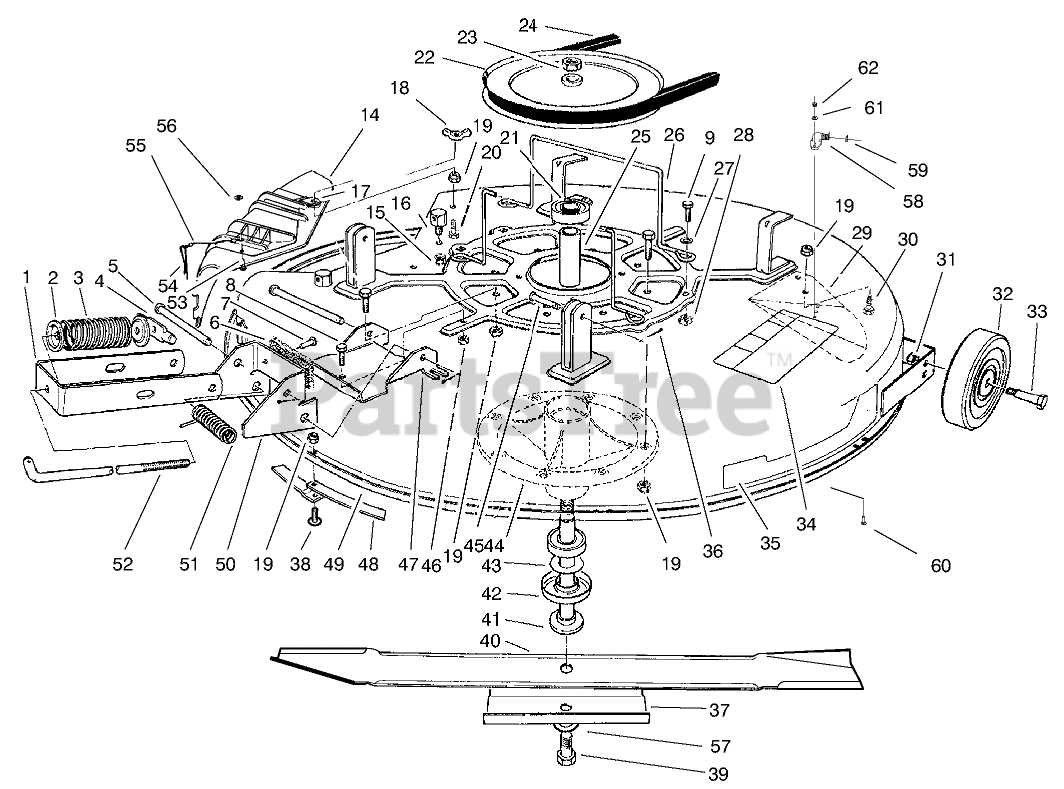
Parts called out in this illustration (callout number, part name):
1	Bracket-Engagement
2	RETAINER-SPR. TOP
3	SPRING-COMPRESSION
4	SHAFT-DECK ADJ.
5	PIN-CLEVIS
6	PAD-BRAKE
7	RIVET-BLIND
8	SCREW-HH
9	SCREW-HH
14	Assy.-Cover, Discharge (Incl. Ref. #53-56)
15	NUT-LOCK, NI
16	POST-PIVOT
17	Brace-Cover, Rear
18	NUT-WING
19	NUT-LOCK, NI
20	SCREW-HH
21	BEARING-BALL
22	PULLEY
23	NUT-HEX
24	V-BELT, DECK
25	SPACER-BEARING
26	GUIDE-BELT
27	WASHER-PLAIN
28	NUT-RETAINER
29	Kicker
30	SCREW-HH
31	NUT-LOCK, NI
32	WHEEL-DECK
33	BOLT-WHEEL
34	DECAL-DANGER
35	DECAL-RECYCLER
36	PIN-COTTER
37	STIFFENER
38	SCREW-PPH
39	SCREW-HH
40	BLADE-RECYCLER
41	SHAFT-SPINDLE
42	SHIELD-BEARING
43	SPACER-HARDNED
44	SPINDLE
45	PIN-CLEVIS
46	NUT-HEX
47	Plate-Deck, Brake Mtg.
48	RING-DECK
49	Deck-Cutting, Recycler (Incl. Ref. #34)(Serial No. 6900001-7900999)
49	Deck Assembly (Incl. Ref. #34 pg.12 & 5 pg. 14)(Serial No. 7901000 & Up)
50	Assembly-Brake (Incl. Ref. #6-7)
51	SPRING
52	ROD-ENGAGEMENT
53	RIVET-BLIND
54	PIN-LOCKING, CHUTE
55	LANYARD
56	WASHER-PLAIN
57	WASHER-BELLEVILLE
58	FITTING-WASHOUT
59	O-RING
60	BOLT-CARR
61	WASHER-FLAT
62	NUT-LOCK, NI
